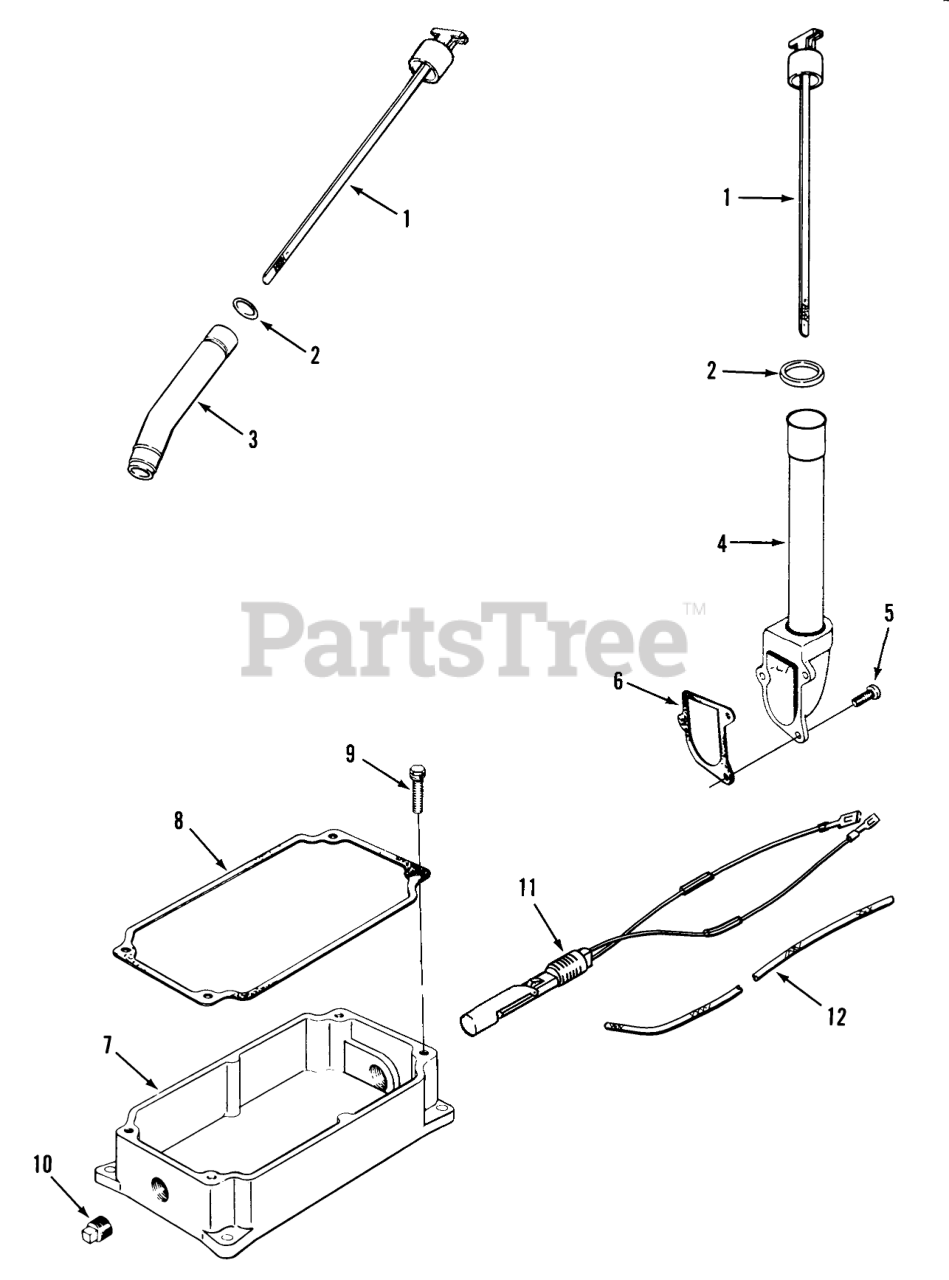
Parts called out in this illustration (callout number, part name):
1	Dipstick 12-13/16 308 Only
2	0-Ring
3	Oil Fill Tube 308 Only
4	Adapter-Oil Fill
5	Screw
6	Gasket
7	Oil Pan 308 Only
8	Oil Pan Gasket 308 Only
9	H.C. Screw 5/16-18 x 1-1/8 308
10	Sq. Hd. Plug 1/2 NPTF 308 Only
11	Float Switch Kit (includes items 12 & Decal) 310, 312, 414, 416
12	Sleeve
